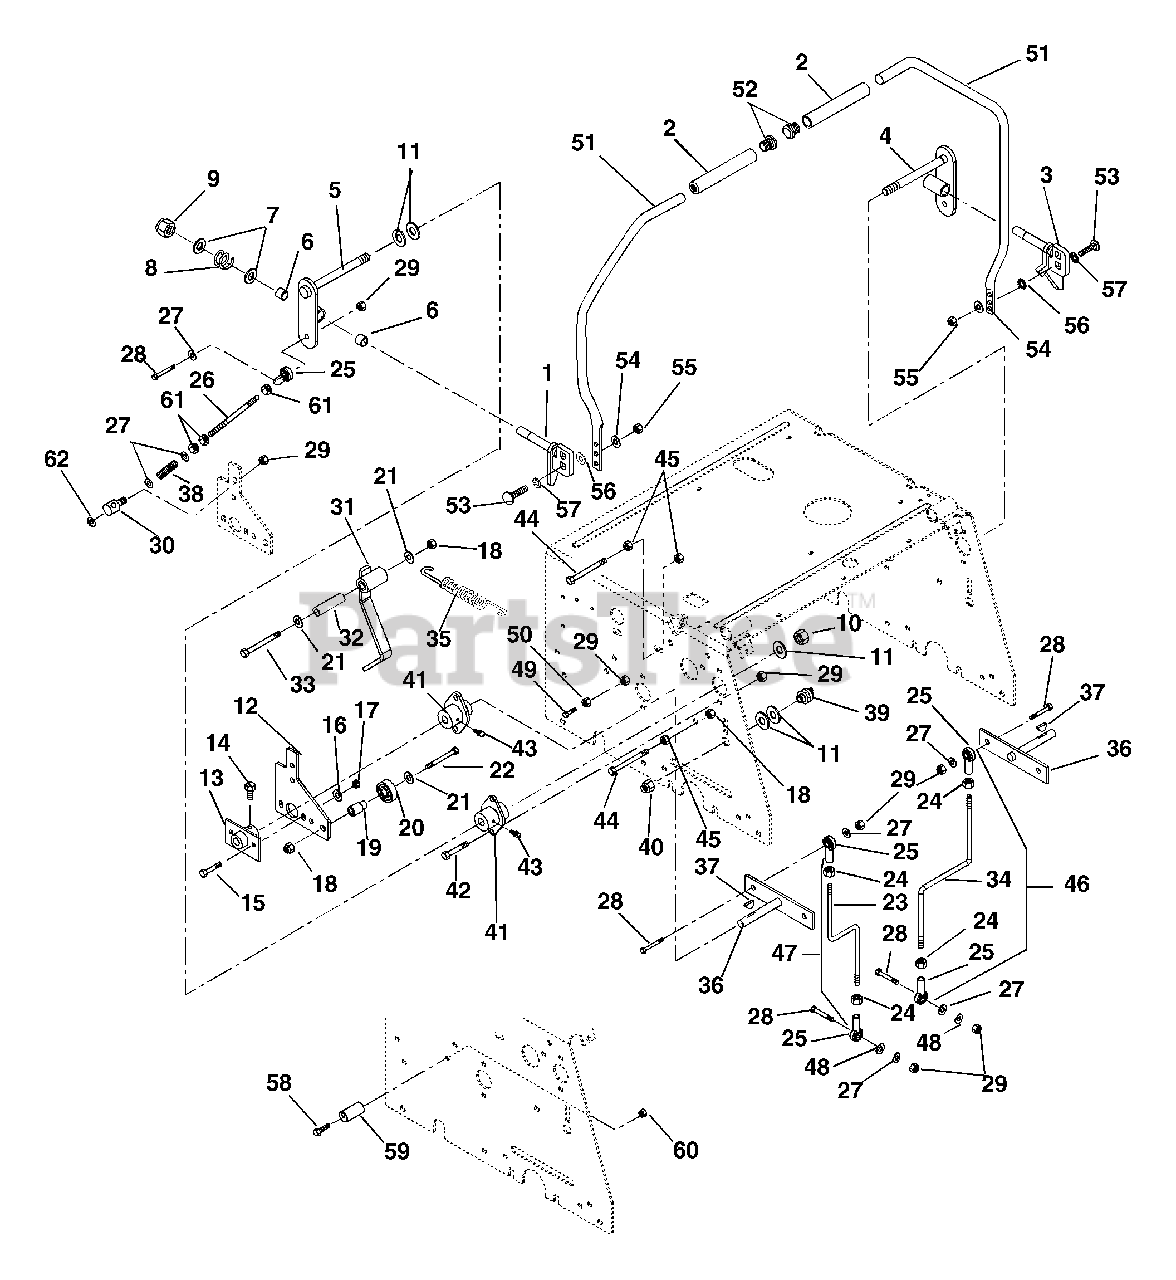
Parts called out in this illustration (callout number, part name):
1	Weldment-Lever Right Hand
2	Grip-Handlebar
3	Weldment-Lever Left Hand
4	Weldment-Rod Left Hand
5	Weldment-Tube Right Hand
6	Bushing-Nylon .5 x .625 x .5
7	Washer-Plastic .12 x .53 x 1.12
8	Spring-Compression
9	Nut-Locking Cone .50-13
10	Nut-Locking-Center .50-20
11	Washer-Flat, Steel .563 x 1.375 x .109
12	Arm-Speed Control
13	Arm-Speed Control
14	Bolt-Hex .25-20 x .50 Grade 5
15	Bolt-Hex .25-20 x .75 Grade 5
16	Washer-Flat Steel .281 x .620 x .065
17	Nut-Locking-Center .250-20
18	Nut-Locking-Center .375-16
19	Hub-Bearing Mount
20	Bearing-Ball .500 x 1.375 x .437
21	Washer-Flat, Steel .406 x .812 x .065
22	Bolt-Hex .38-16 x 2.00 Grade 5
23	Rod-Transaxle Right Hand
24	Nut-Jam .31-24
25	Rod-End-Female .312
27	Washer-Flat-Steel .344 x .688 x .065
28	Bolt-Hex .31-18 x 1.00 Grade 5
29	Nut-Locking-Center .312-18
30	Rod-Pivot
31	Weldment-Neutral Detent
32	Bushing-Sleeve .385 x .610 x 1.80
33	Bolt-Hex .38-16 x 2.75 Grade 5
34	Rod-Transaxle Left Hand
35	Spring, Tension .085 x .60 x 5.13
36	Weldment-Pump
37	Key-Woodruff .13 x .75
39	Switch-Neutral
40	Nut-Stamped .56-18
41	Bushing-Flanged
42	Bolt-Hex .31-18 x .75 Grade 5
43	Fitting-Lube .25-28 x .256
44	Bolt-Hex .38-16 x 3.00
45	Nut-Hex .375-16 Grade 2
46	Rod Assembly-Transaxle Right Hand
47	Rod Assembly-Transaxle Left Hand
48	Washer-Flat-Steel .347 x 1.254 x .048
49	Bolt-Hex .31-18 x .75
50	Nut-Hex .31-18
51	Handlebar-Large Frame
52	Cap Plug-Handlebar
53	Bolt-Round Head Square Neck .31-18 x 1.00 Grade 5
54	Washer-Flat-Steel .38 x .875 x .083
55	Nut-Locking-Flange .31-18
56	Washer-Locking-External .326 x .599 x .031
57	Washer-Locking-Internal .438
58	Bolt-Hex .31-18 x 2.75 Grade 5
59	Eccentric
60	Nut-Locking-Nylon .31-18
61	Nut-Hex .31-24
62	Washer-Flat-Steel .38 x 87 x .179
